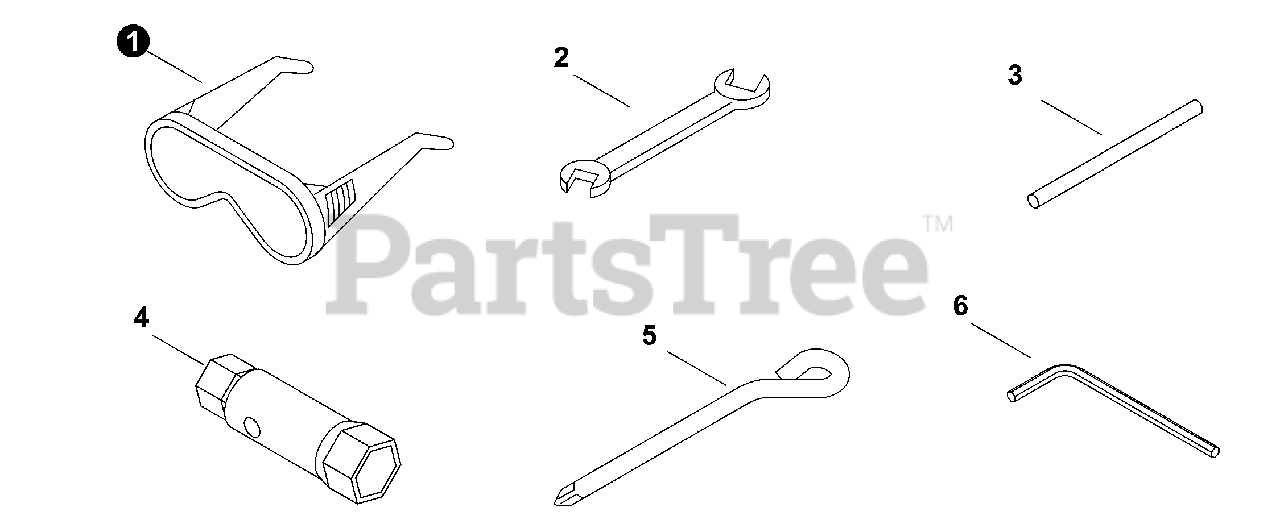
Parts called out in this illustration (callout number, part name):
1	GLASSES, SAFETY
2	SPANNER
3	TOOL, LOCKING
4	WRENCH, SOCKET
5	SCREWDRIVER
6	WRENCH, ALLEN
